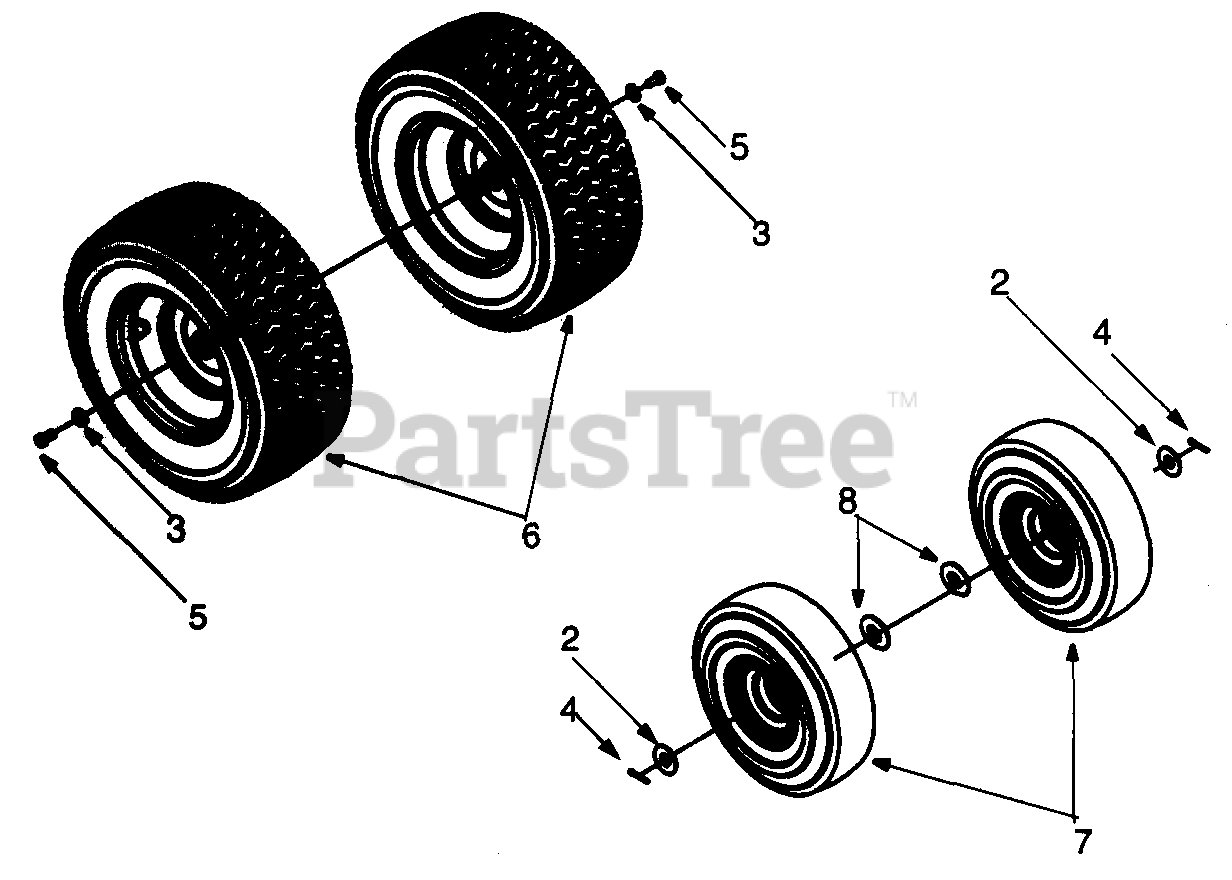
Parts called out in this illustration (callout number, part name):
2	Flat Washer .635 x 1.589 x .060
3	Bell Washer .345 I.D. x .88 O.D. x .06
4	Hairpin Clip
5	Hex Screw 5/16-24 x .75
